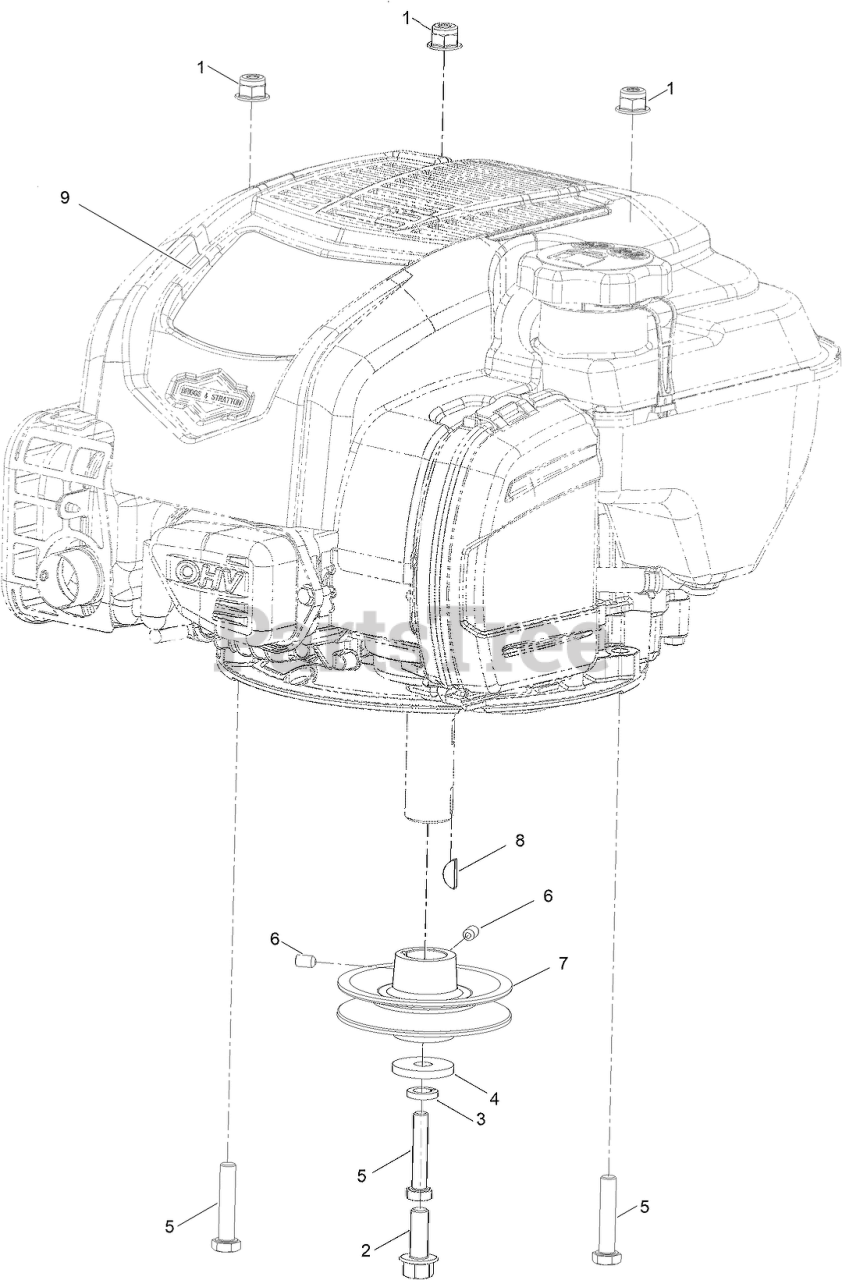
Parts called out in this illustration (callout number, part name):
1	NUT-HEX
2	SCREW-HHF
3	WASHER-LOCK
4	WASHER-PLAIN
5	SCREW-HH
6	SCREW-SET
7	PULLEY-TRACTION, ENGINE
8	WOODRUFF KEY
9	DECAL-ENGINE
